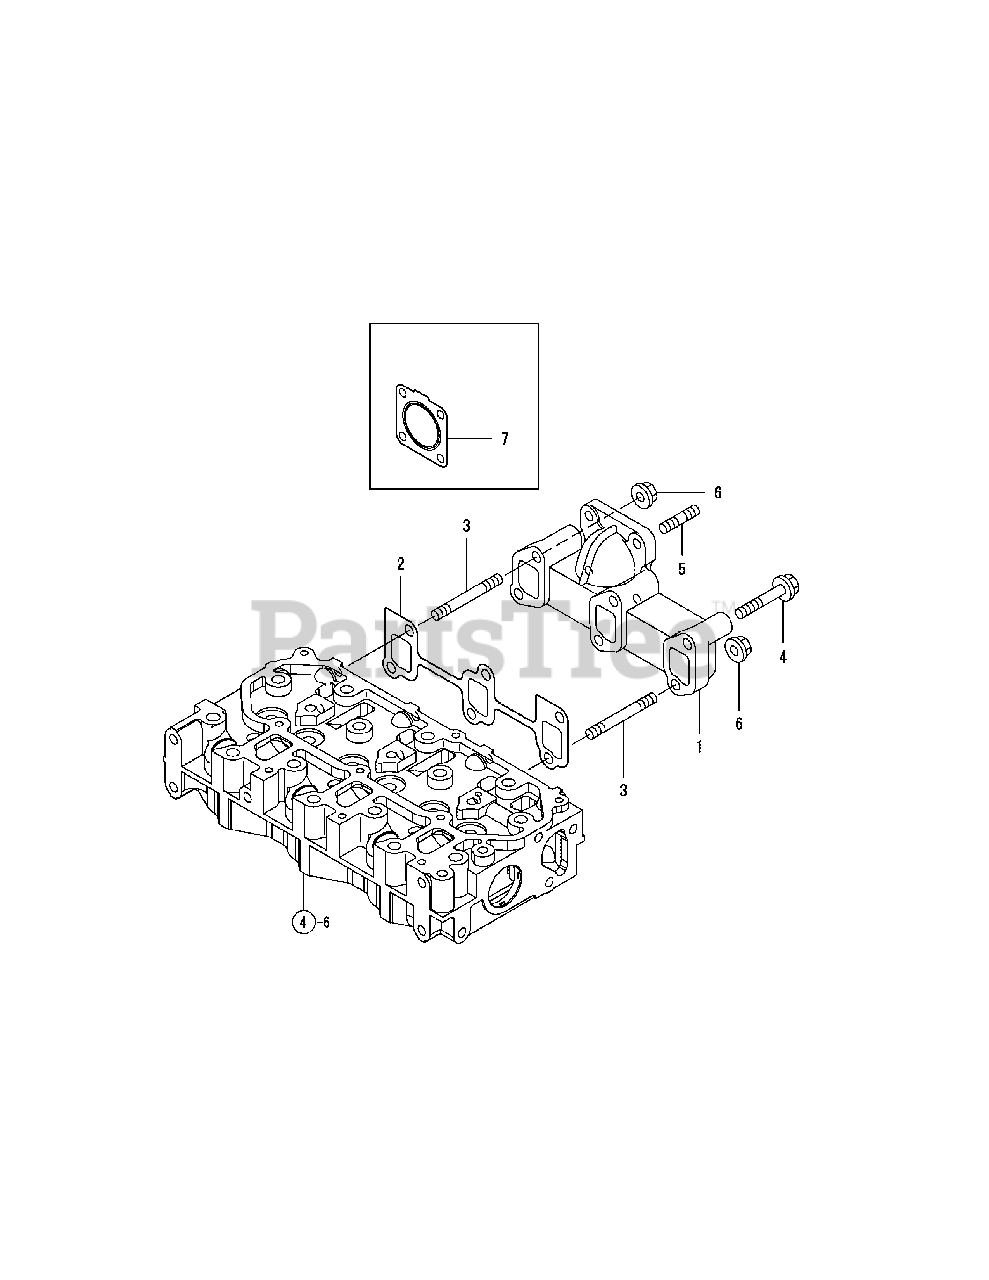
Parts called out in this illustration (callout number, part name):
1	Manifold, Exhaust
2	Gasket, Manifold
4	Bolt, M 8 x 50 Plated
5	Bolt, M 8 x 22
7	Gasket, Silencer
